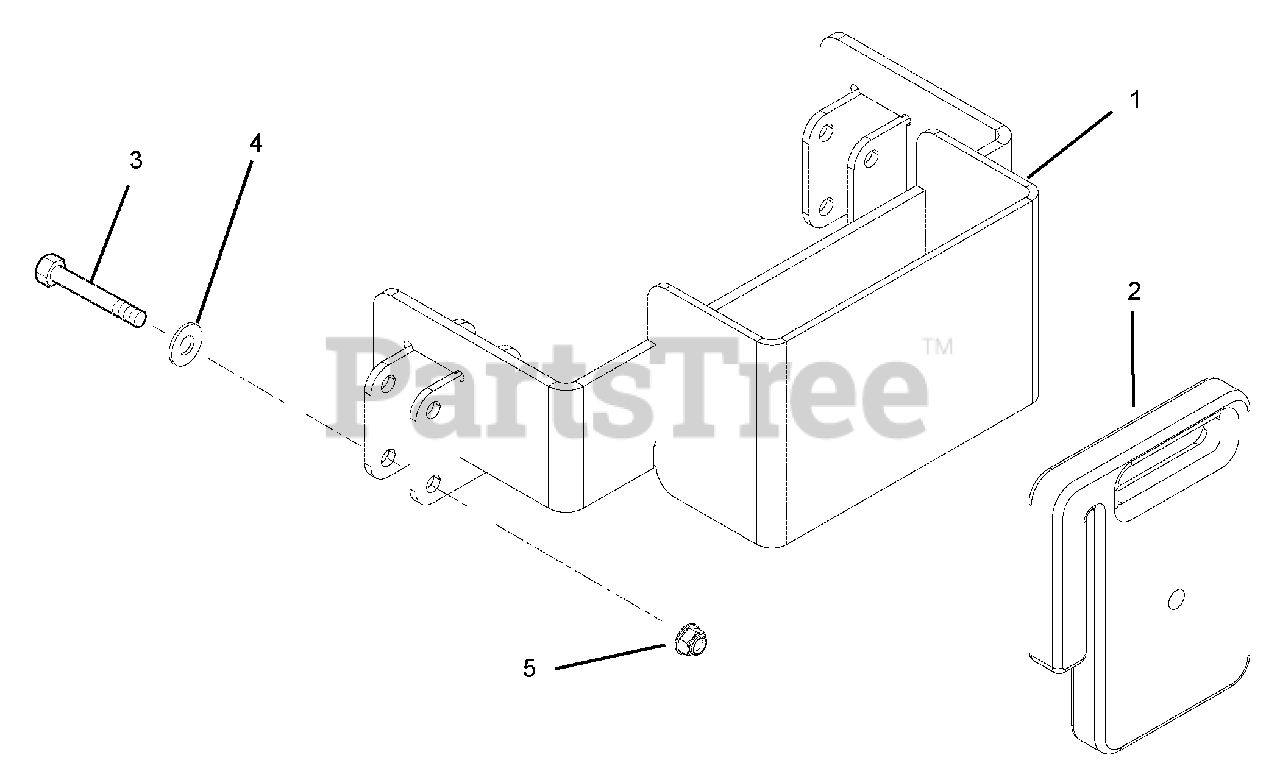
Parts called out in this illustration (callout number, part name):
1	WMT, BAGGER WEIGHT BRACKET
2	WEIGHT, REAR
3	@BLT-HEX .38-16X2.25 GR5 YWZC
4	WSHR-FL-STL .406X1.00X.188 YWZ
5	@NUT-LK-NYL-FLG .38-16 YWZC
